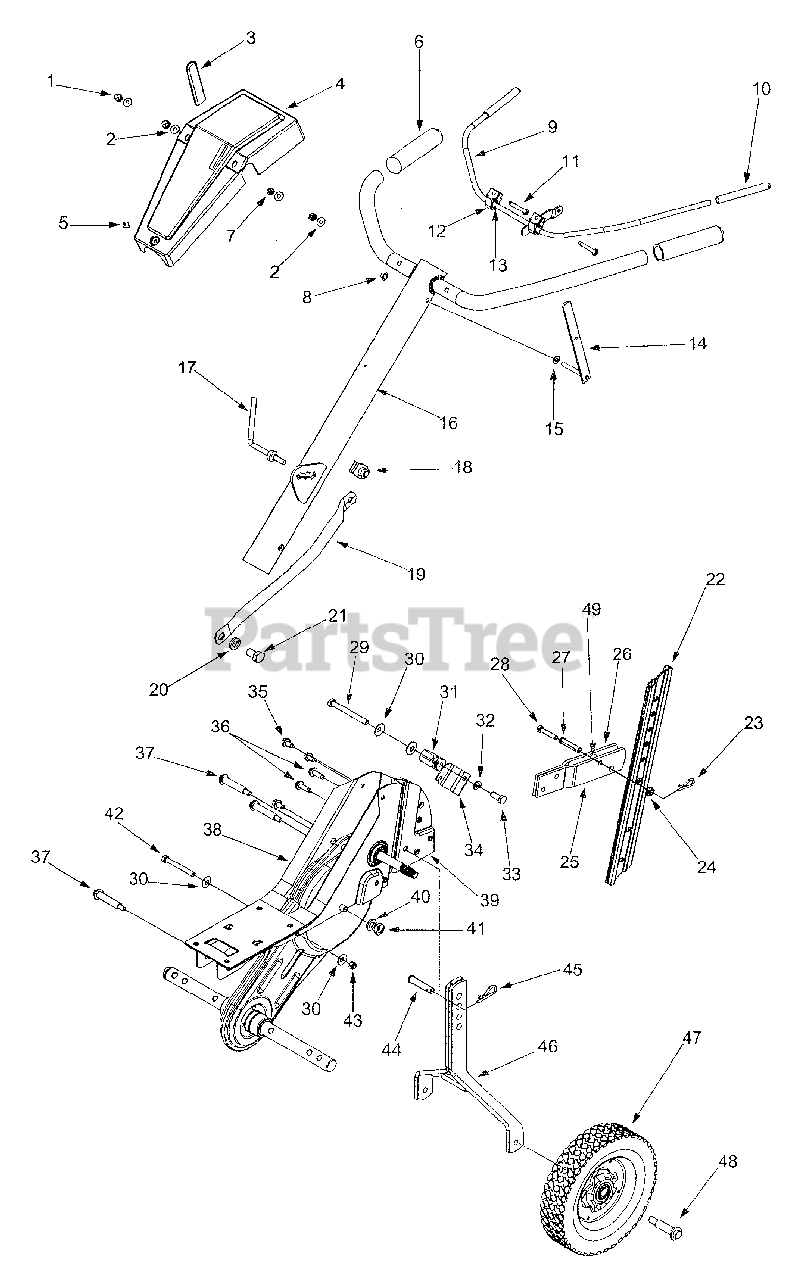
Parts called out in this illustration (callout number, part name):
1	Acorn Lock Nut 1/4-20
2	Flat Washer .271" I.D. x .630" O.D.
3	Reverse Handle Grip
4	Handle Cover
5	Truss Mach. Scr. #10 x 1/2" Lg.
6	Grip-Handle
7	Hex Nut 1/4-20 Gr.2
8	Cap Speed Nut
10	Grip-Clutch
11	Hex Bolt 1/4-20 x 2.25" Lg. Gr.5
12	Clutch Handle Holder
13	Flat Washer .385" I.D. x .62" O.D.
15	Flat Washer .344" I.D. x .62" O.D.
18	U Nut 5/16-18
21	Hex Bolt 1/2-20 Gr. 5
23	Cotter Pin
24	Hex Flange L-Nut 5/16-18
27	Clevis Pin
28	Hex Bolt 5/16-18 x 1.5" Lg.
29	Hex Bolt 5/16-18 x 3" Lg.
30	Wash. Bell. .340" I.D. x .872" O.D.
31	Spec. Hex Nut
32	L-Wash. 5/16" I.D.
33	Hex Bolt 5/16-18 Gr. 5
35	Hex Wash Screw 5/16-18 x .62"
36	Hex Wash. Hd. TT Tap Scr.
37	Shdl. Bolt 5/16-18
40	Lock Washer 7/16
41	Jam Nut 7/16-20 Gr. 2
42	Hex Bolt 5/16-18 x 2.75" Lg.
43	Hex Nut 5/16-18 Thd.
44	Clevis Pin
45	Cotter Pin
47	Wheel Ass'y 8" x 1.75"
48	Shoulder Screw .496 x 1.445
